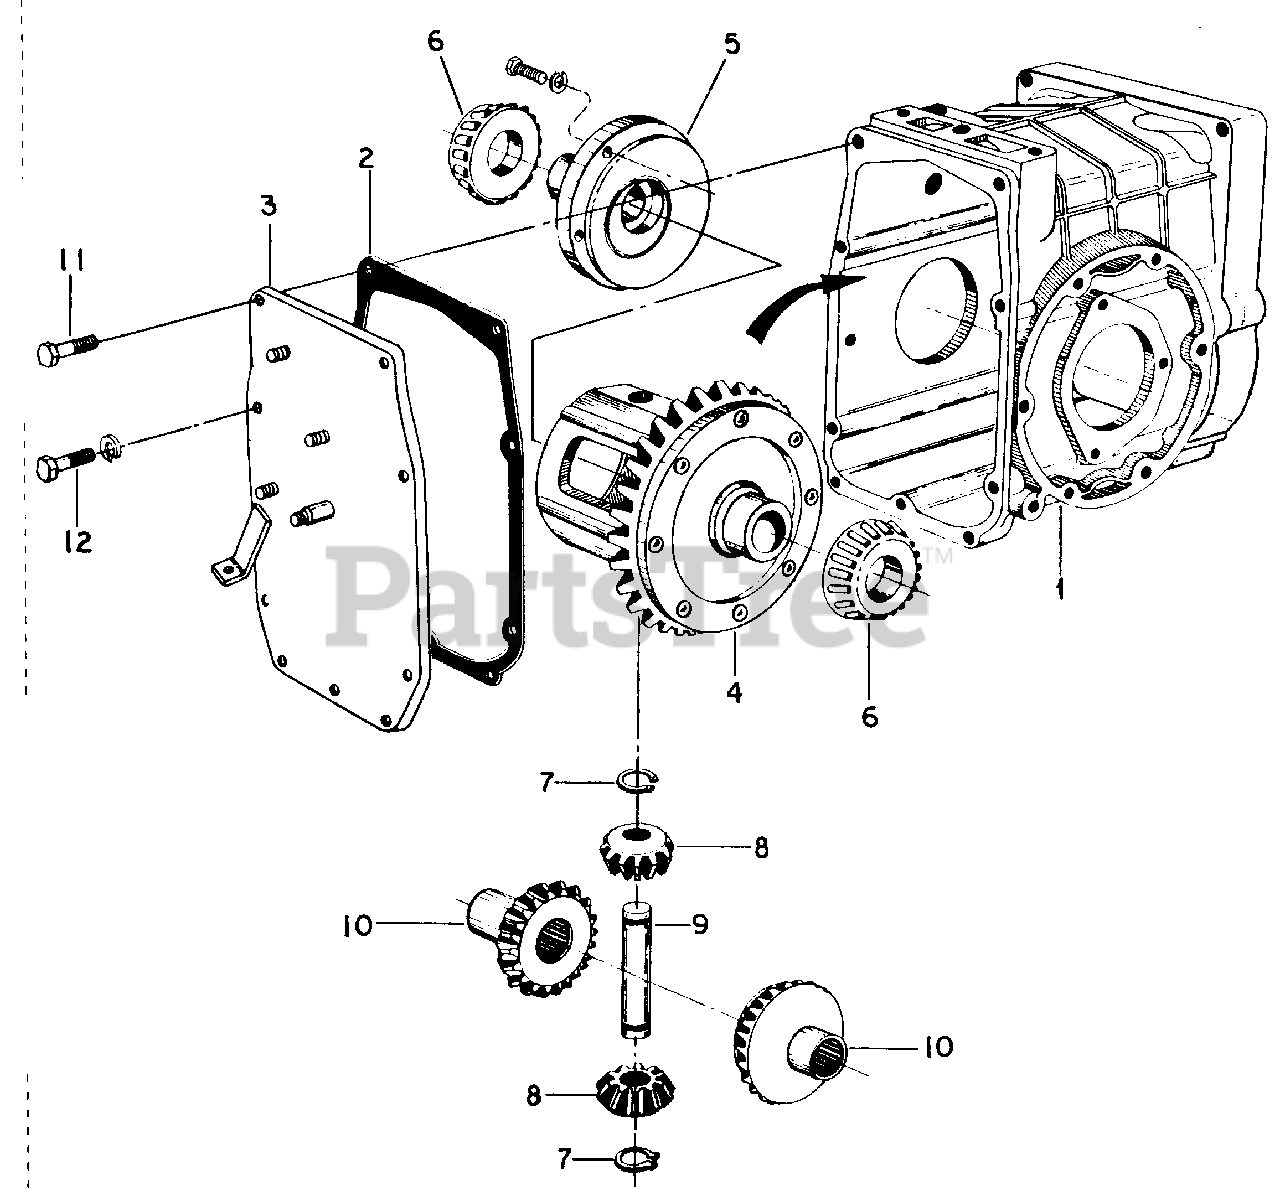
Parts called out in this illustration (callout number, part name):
1	Housing Assy, Rear w/Needle Bearing
2	Gasket, Rear Cover Plate
3	Plate, Rear Cover
4	Gear Assy, Ring w/Case
5	Plate, Diff Flange
6	Bearing Assy, Differential Cone
7	Ring, .616 Hwy Ext Ret
8	Pinion, Differential -10T
9	Shaft, Cross
10	Gear, Side -16T
11	Bolt, 3/8 X 5/8 Type 5
12	Bolt, 3/8 X 3/4 Type 5
